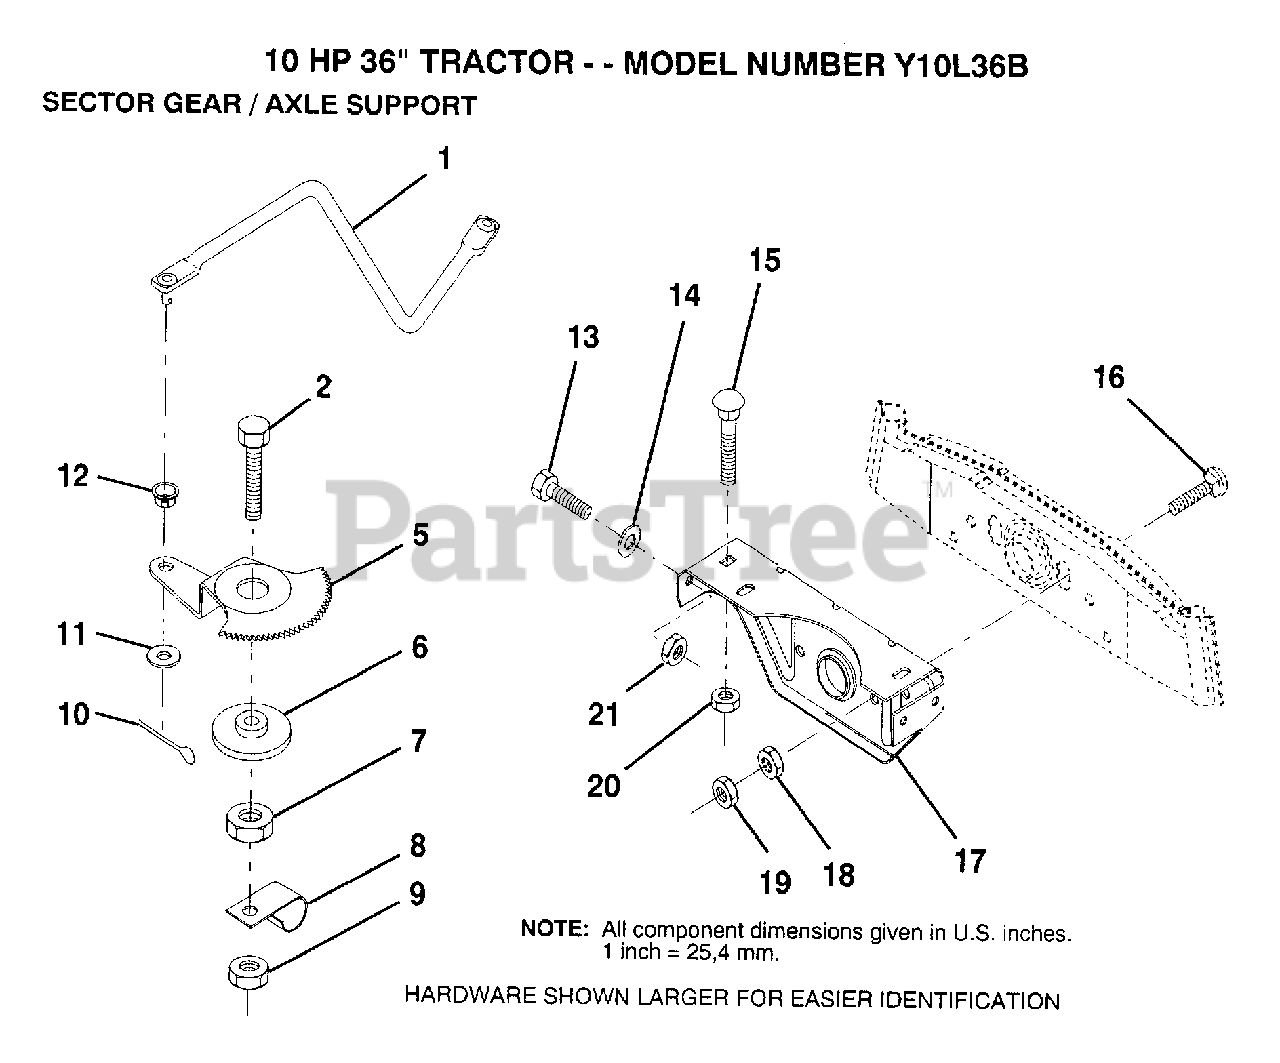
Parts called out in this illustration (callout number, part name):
1	DRAG LINK
2	"BOLT,HEX"
5	GEAR SECTOR
6	BUSHING
7	NUT
8	CLIP INSULATOR
9	NUT LTV
10	COTTER PIN
11	WASHER
12	BUSHING.DRAGLINK
13	BOLT
14	WASHER
15	BOLT
16	BOLT
17	"SUPT,FRT AXLE"
18	NUT.HEX.3/8-16UNC
19	LOCKNUT
